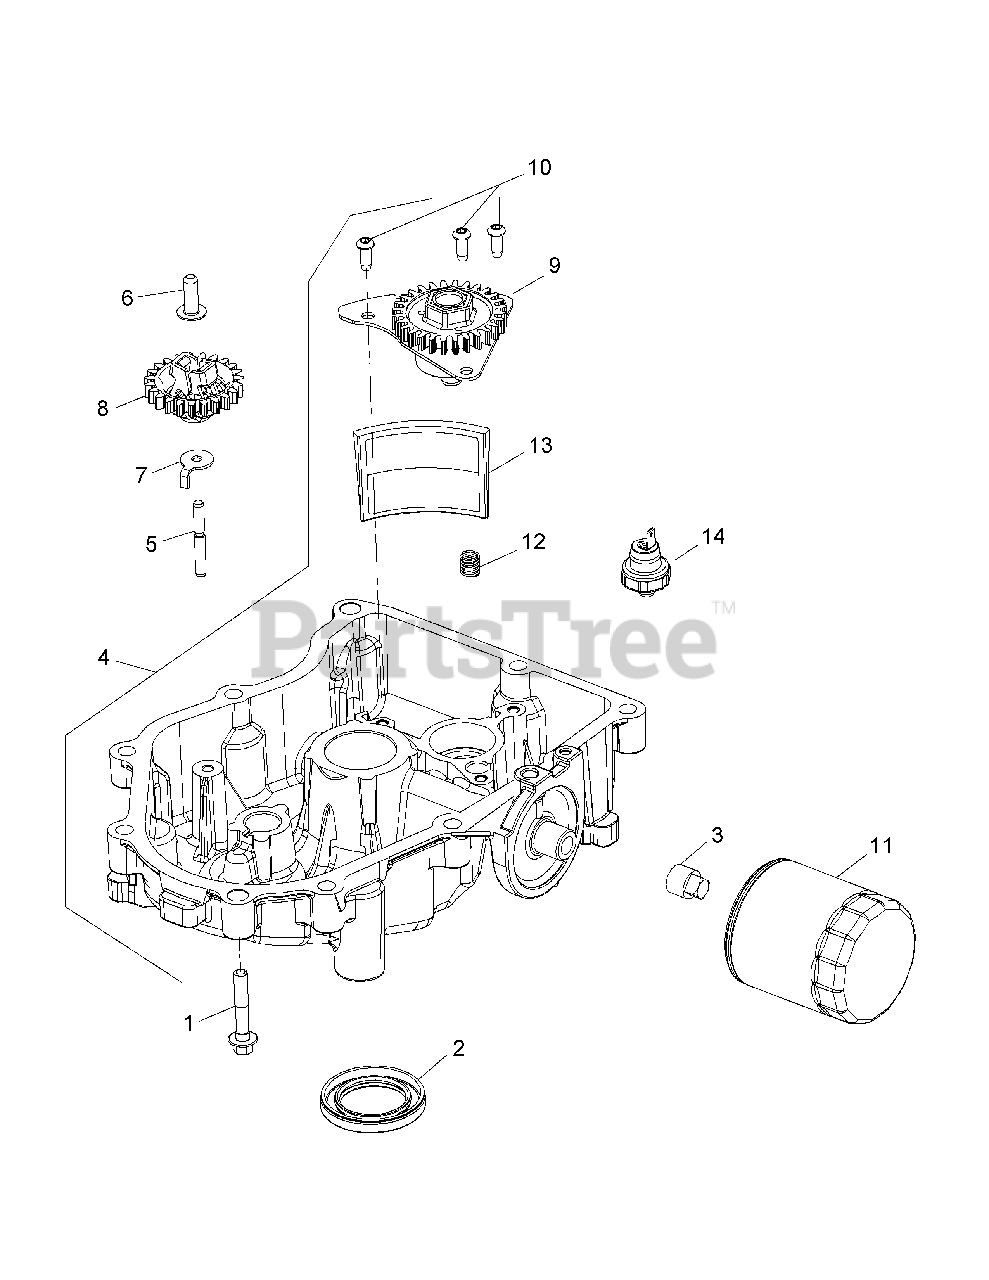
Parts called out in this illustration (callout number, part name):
1	Flange Screw, M8 x 1.25 x 45
2	Oil Seal, 2.38 x 1.45
3	Square Head Pipe Plug, 3/8
4	Oil Pan Assembly
5	Governor Gear Shaft
6	Governor Regulating Pin
8	Governor Gear Kit
9	Oil Pump Assembly
10	Button Head Screw
12	Compression Spring
14	Oil Pressure Switch
